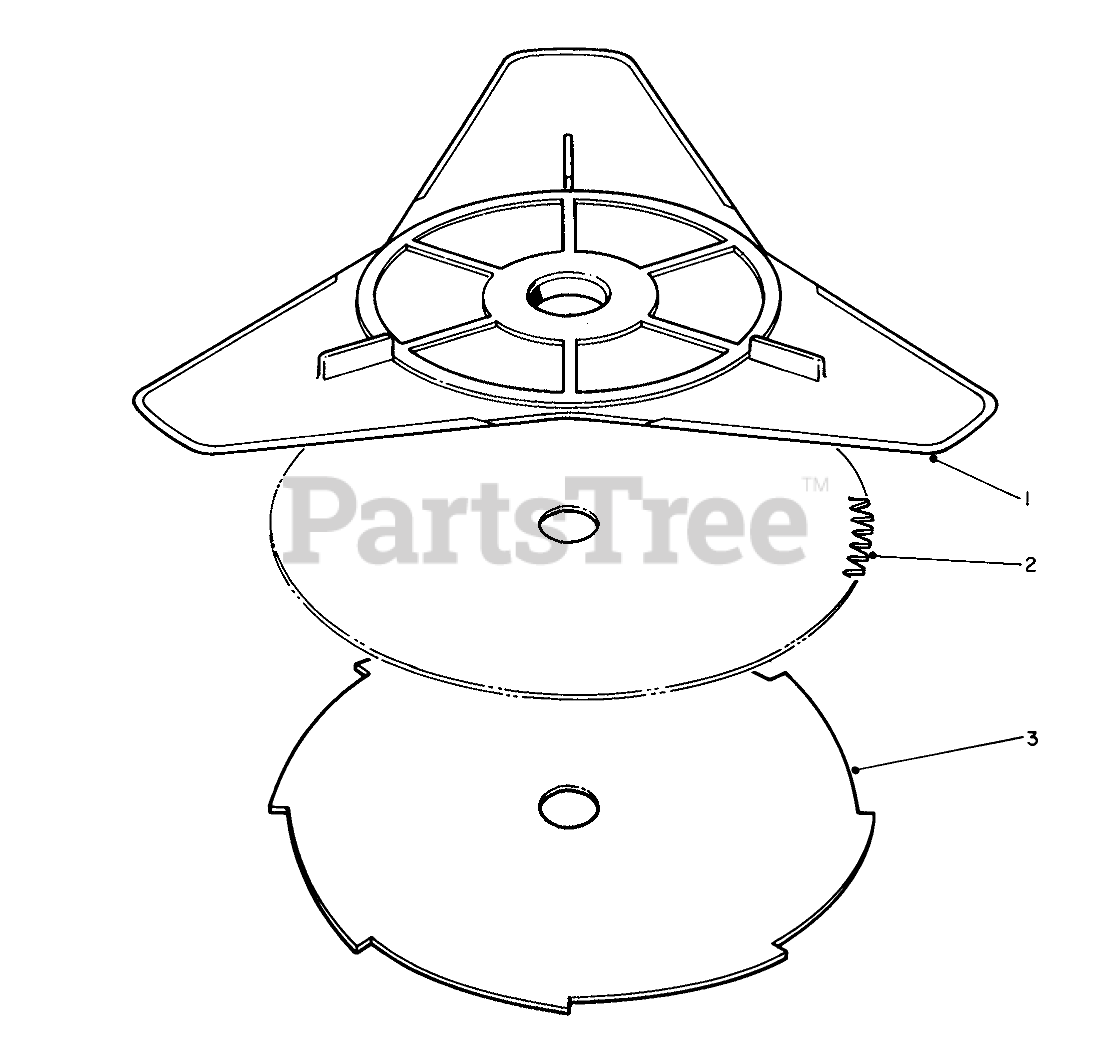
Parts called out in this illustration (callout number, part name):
1	FLEX BLADE PKG
2	SAW BLD PKG(8", 80T)
3	BRUSH BLD PKG(8",8T)
